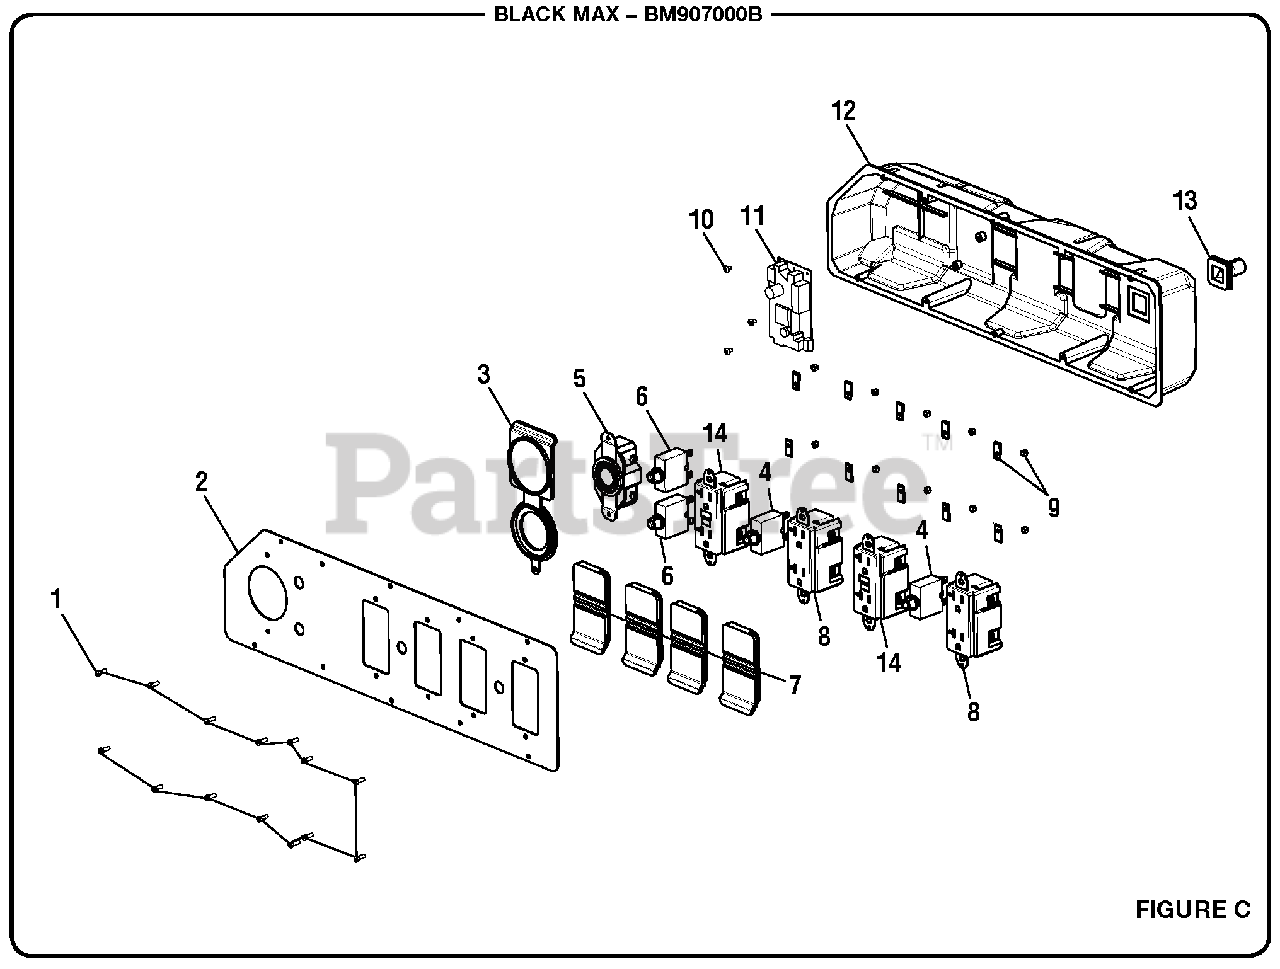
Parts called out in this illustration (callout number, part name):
1	Screw (6-20 x 3/8 in., Pan Hd.)
2	Faceplate
3	Twist Lock Receptacle Cover
4	Circuit Breaker (20A)
5	120/240V Receptacle (30A)
6	Circuit Breaker (30A)
7	120V Duplex Receptacle Cover
8	120V Duplex Receptacle
9	Lock Nut (6-32, Hex Hd.)
10	Screw (M3 x 5 mm)
11	Battery Charger
12	Control Box
13	Rubber Wire Protector
14	120V GFCI Duplex Receptacle
